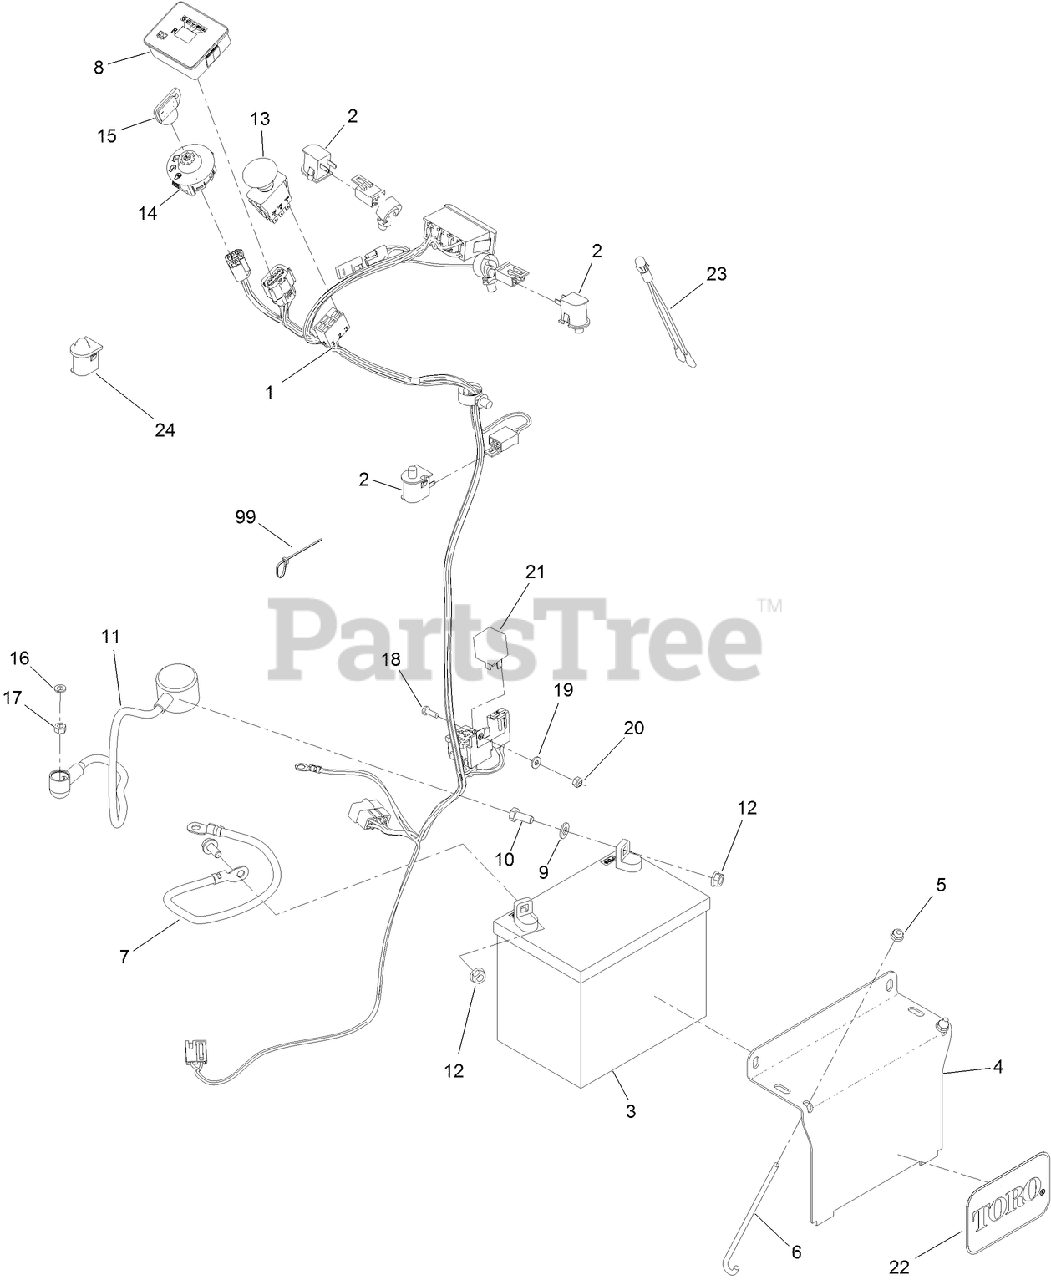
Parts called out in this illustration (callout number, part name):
1	HARNESS-WIRE
2	SWITCH-BAIL
3	BATTERY-DRY
4	BRACKET-HOLD DOWN, BATTERY
5	NUT-HF
6	BOLT-HOLDDOWN
7	CABLE-BATTERY, BLACK
8	MODULE-METER, HOUR
9	WASHER-PLAIN
10	SCREW-HH
11	CABLE-BATTERY, POSITIVE
12	NUT-HHF, SMOOTH
13	SWITCH-PTO, ON-ON
14	SWITCH-IGNITION
15	KEY-IGNITION
16	SCREW-HH
17	NUT-HEX
18	SCREW-PPH
19	WASHER-FLAT
20	NUT-LOCK, NI
22	DECAL
23	INDICATOR-LED, RED
24	SWITCH-PLUNGER
99	TIE-CABLE
